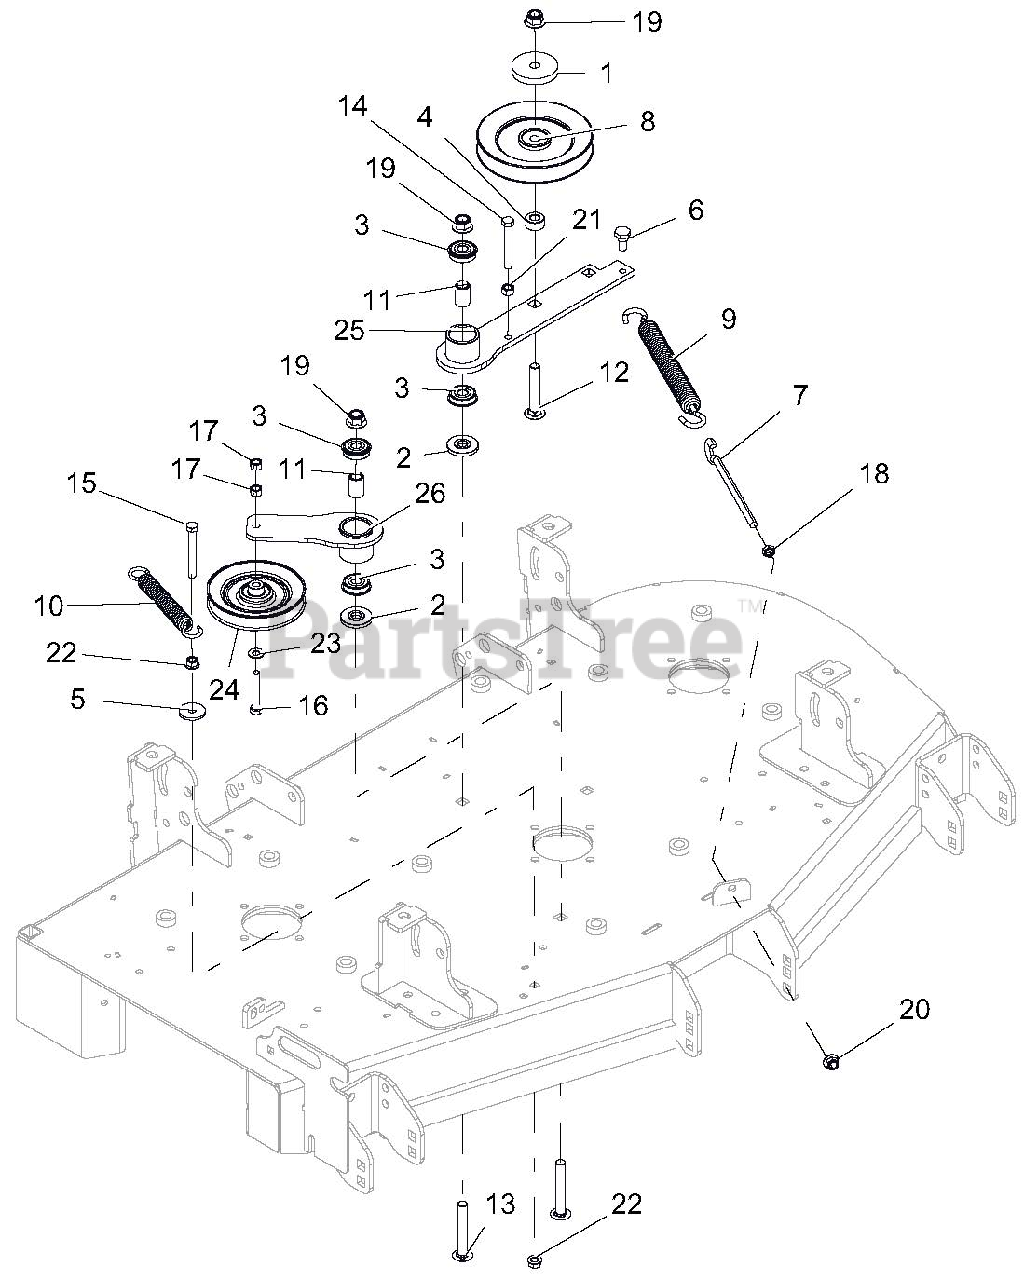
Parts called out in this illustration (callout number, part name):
1	CAP, IDLER BEARING SEALING
2	SPACER, IDLER ARM
3	BRG, BALL .501 X 1.38 X .438 SEALED
4	BSHG, SPCR .502 X .997.50 PM
5	WSHR-FL-STL .406X1.375X.135 YZ
6	BLT, SHLDR EP .38-16X.30 HEX YZ
7	BOLT, .38-16X6.00 .62 DIA EYE
8	SHEAVE, .50" ID X 6.00" OD V-IDLER
9	SPRG, EXTENSION
10	SPRG, EXTENSION
11	SPACER, .510 X .750 X 1.148
12	BLT-RDHDSQNK .50-13X3.00 G5 Y
13	BLT-RDHDSQSHNK .50-13X3.25 YWZC
14	BLT-HEX .38-16X2.75 GR5 YWZC
15	BLT-HEX .38-16X3.00 GR5 YWZC
16	BLT-HEX .38-16X2.25 GR5 YWZC
17	NUT-LK-CTR .38-16 YWZC
18	NUT, JAM .375-16 YWZC
19	NUT-LK-NYL-FLG .50-13 YWZC
20	NUT-LK-NYL-FLG .38-16 YWZC
21	NUT-HEX .38-16 YWZC
22	@NUT-SPNLK-FLG .375-16 YWZC
23	WSHR-FL-STL.406X.812X.065 YWZ
24	IDLER, V-5.00" W/.69 STANDOFF
25	WLDMT, DECK PTO IDLER ARM-BLACK
26	WLDMT, DECK RH IDLER ARM-BLACK
